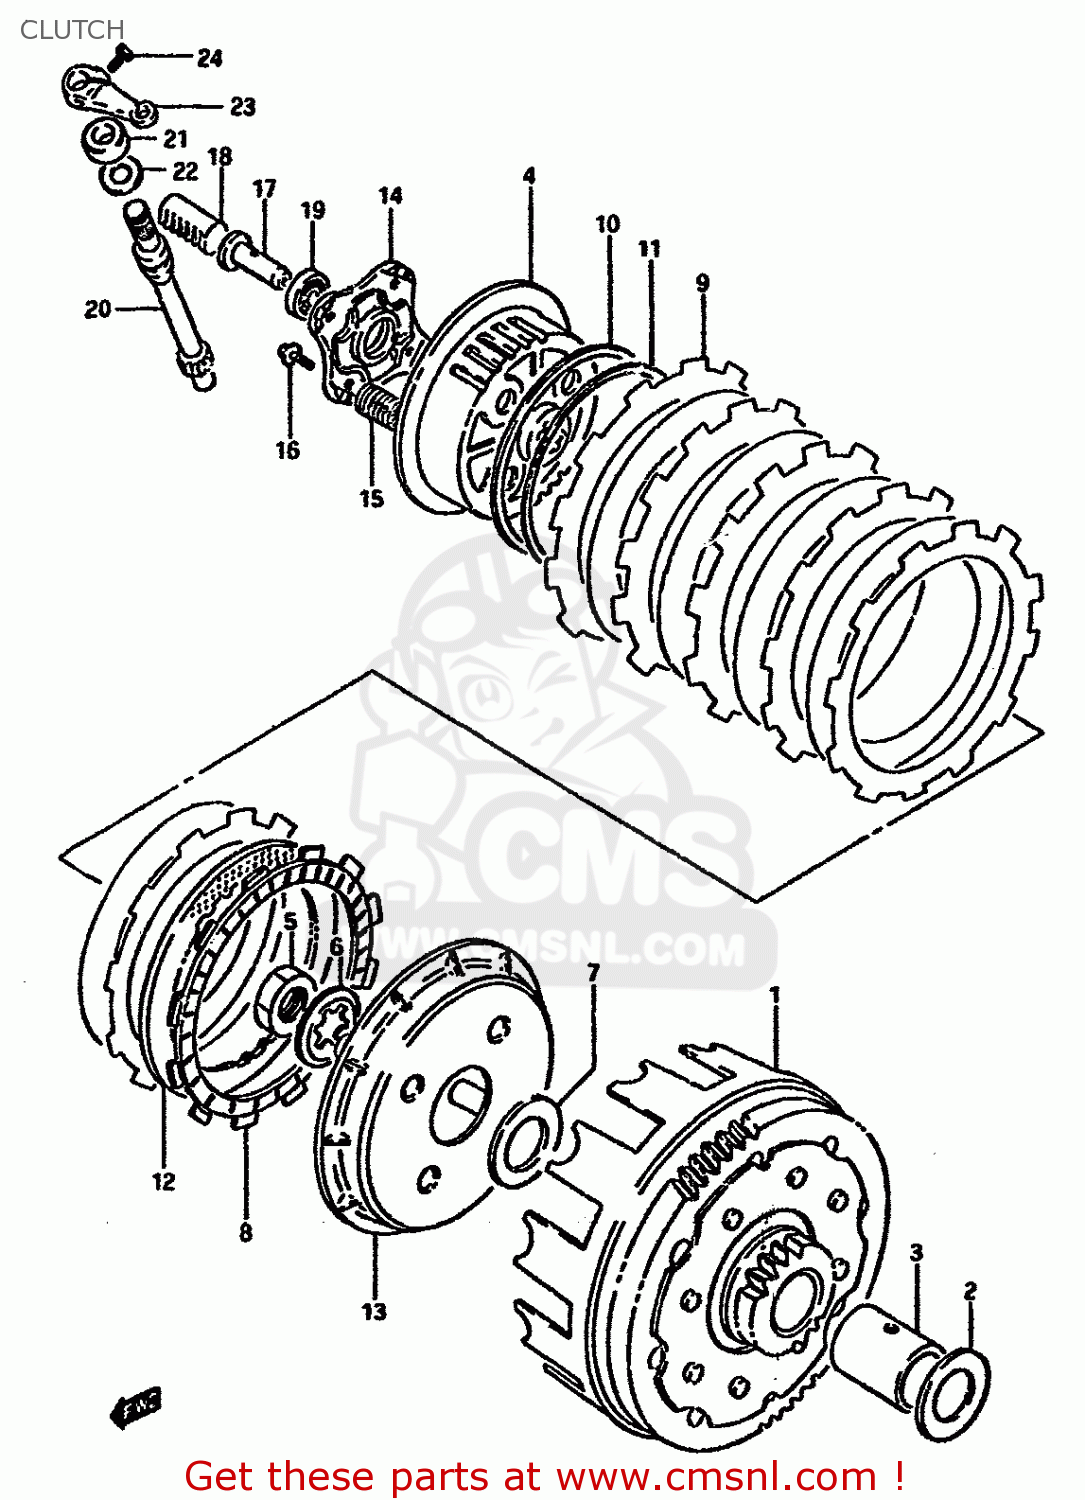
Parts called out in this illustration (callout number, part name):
1	GEAR ASSEMBLY,PRIMARY DRIVE
2	WASHER
3	SPACER(22X28X32.5)
4	HUB,CLUTCH SLEEVE
5	NUT
6	WASHER,LOCK
7	WASHER
8	PLATE,CLUTCH DRIVE (NAS)
9	PLATE,CLUTCH DRIVE(T:3.5) (NAS)
10	SEAT,WAVE WASHER(T:1.4)
11	WASHER
12	PLATE,CLUTCH DRIVEN(T:1.6) (NAS)
13	DISC,CLUTCH PRESSURE
14	PLATE,RELEASE
15	SPRING
16	BOLT 6X20
17	PIECE,CLUTCH PUSH
18	RACK,CLUTCH RELEASE
19	BEARING
20	PINION,CLUTCH RELEASE
21	SEAL,OIL (12X22X9)
22	WASHER (14.2X22X1)
23	ARM,CLUTCH RELEASE
24	BOLT
